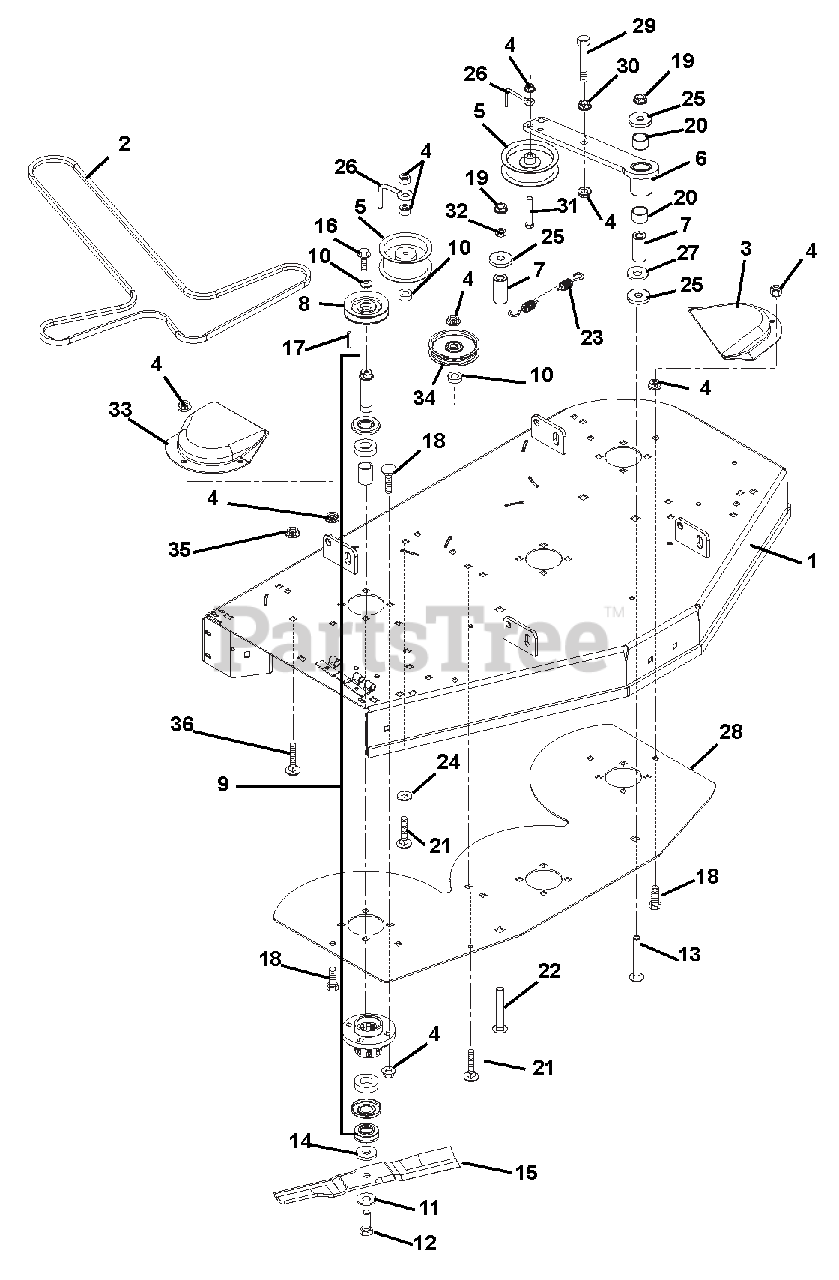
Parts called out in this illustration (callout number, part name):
1	WMT,40"DECK
2	V-BELT, HA-WRAPPED
4	@NUT-LK-NYL-FLG .38-16 YWZC
5	PULLEY, IDLER 4.00
6	WMT, IDLER PIVOT ARM
7	BSHG, SPCR .502X.997X2.03 PM
8	SHEAVE, SPINDLE - 4.00 DIA.
9	ASSEMBLY, SPINDLE
10	WSHR,FLT STL.406X1.50X.245YWZC
11	WSHR-BLVL .669X1.535X.138
12	BLT-HEX .62-18X1.75 GR8 YWZC
13	@BLT-RDHDSQNK .50-13X3.50 G5YZ
14	@WSHR-FL-STL.688X1.75X.134 YWZ
15	MOWER BLADE, 13.94"
16	BLT-HEX .38-16X1.00 YZ GR8
17	KEY, SQ .25 X .38 X .25
18	@BLT-RDHDSQNK .38-16X1.25 G5YZ
19	@NUT-LK-TOP-FLG .50-13 YWZC
20	BRG, 1.00 X 1.12 X .75
21	@BLT-RDHDSQNK .38-16X2.00 G5YZ
22	@BLT-RDHDSQNK .50-13X3.75 G5YZ
23	SG-TENS .187X1.50X9.94 WLD 40
24	@WSHR-FL-STL.531X1.06X.095YWZC
25	WSHR-FL-STL .515X1.625X.250 YZ
26	BELT FINGER
27	WSHR-FL-STL.511X1.441X.125 YWZ
28	PLATE,40"DOUBLER
29	@BLT-HEX .38-16X2.00 GR5 YWZC
30	@NUT-SPNLK-FLG .375-16 YWZC
31	@BLT-HEX .38-16X2.50 GR5 YWZC
32	NUT-SPNLK-FLG .50-13 YWZC
33	BELT COVER
34	IDLER, FLAT .38X4.00X1.06
35	@NUT-LK-NYL-FLG .31-18 YWZC
36	@BLT-RHDSSQNK .31-18X.62 G5YZ
